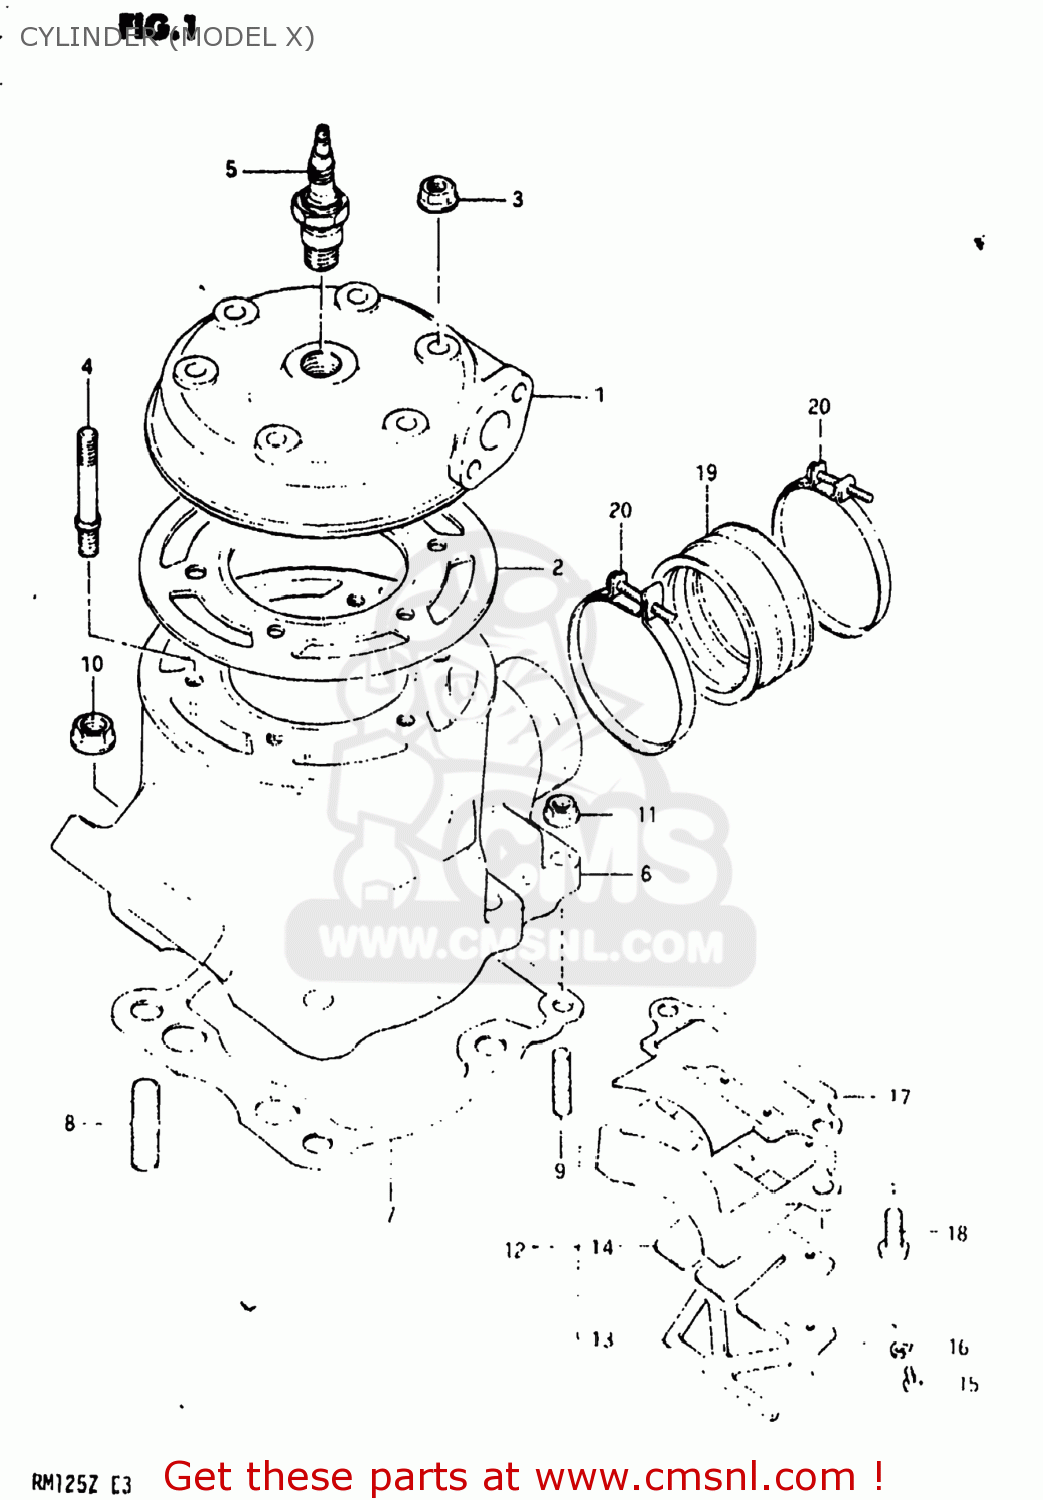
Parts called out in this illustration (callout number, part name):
1	HEAD,CYLINDER
2	GASKET,CYLINDER HEAD (MCA)
3	NUT
4	BOLT,STUD
5	SPARK PLUG
6	CYLINDER
7	GASKET,CYLINDER (MCA)
8	STUD 8X25
9	STUD 6X20
10	NUT
11	NUT
12	VALVE ASSEMBLY,REED
13	STOPPER,REED VALVE
14	VALVE,REED
15	SCREW
16	LOCK WASHER
17	GASKET,REED VALVE (MCA)
18	SCREW
19	PIPE,INTAKE
20	CLAMP
